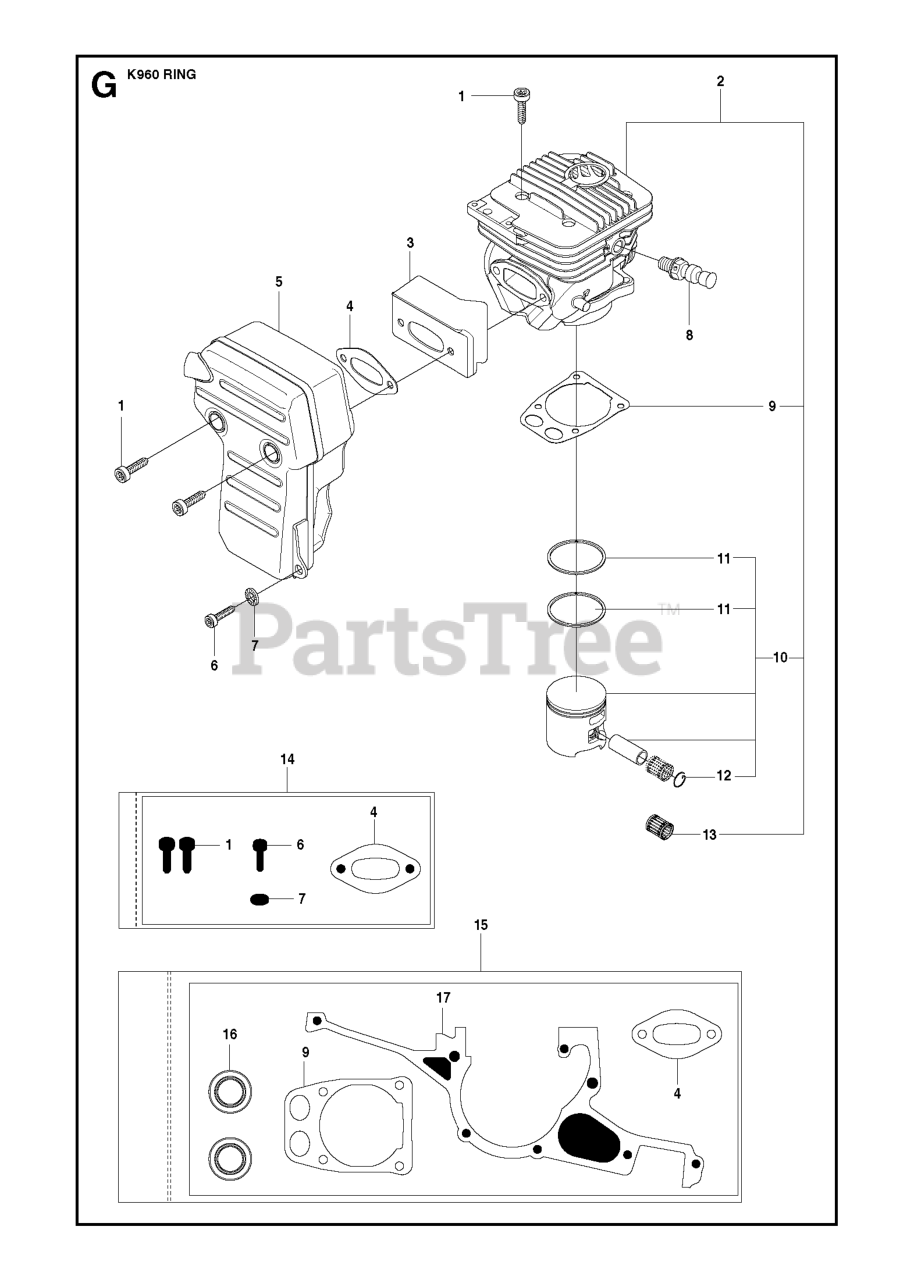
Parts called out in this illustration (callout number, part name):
2	RP CYLINDER ASSY
3	HEAT DEFLECTOR
4	GASKET MUFFLER
5	MUFFLER
7	DOUBLE WASHER
9	RP GASKET
10	PISTON
11	PISTON RING
13	SUPPORT BUSHING
14	MUFFLER MOUNTING KIT K960
15	RP GASKET KIT
16	SEALING RING
17	RP GASKET
